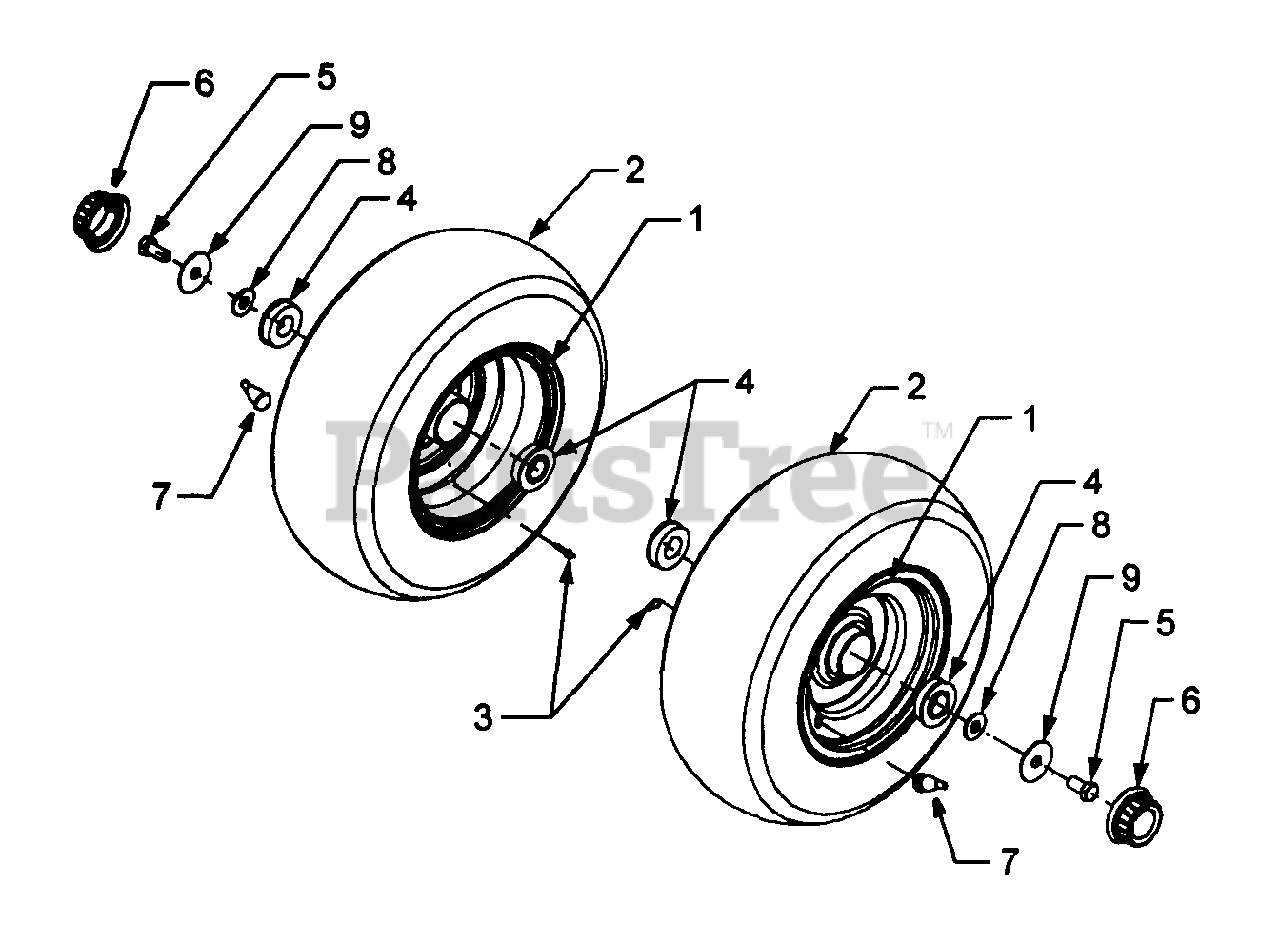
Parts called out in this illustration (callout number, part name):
1	Rim Assembly, Wheel
2	Tire, Turf, 16 x 7.5 x 8.0
3	Lube Fitting
4	Bearing, Ball
5	Screw, Hex Cap, 1/2-13 x 1.0 GR5
6	Hubcap
7	Valve, Tubeless Air
8	Washer, Flat, .531 x 1.25 x .1
9	Washer, Flat, .535 x 1.92 x .060
